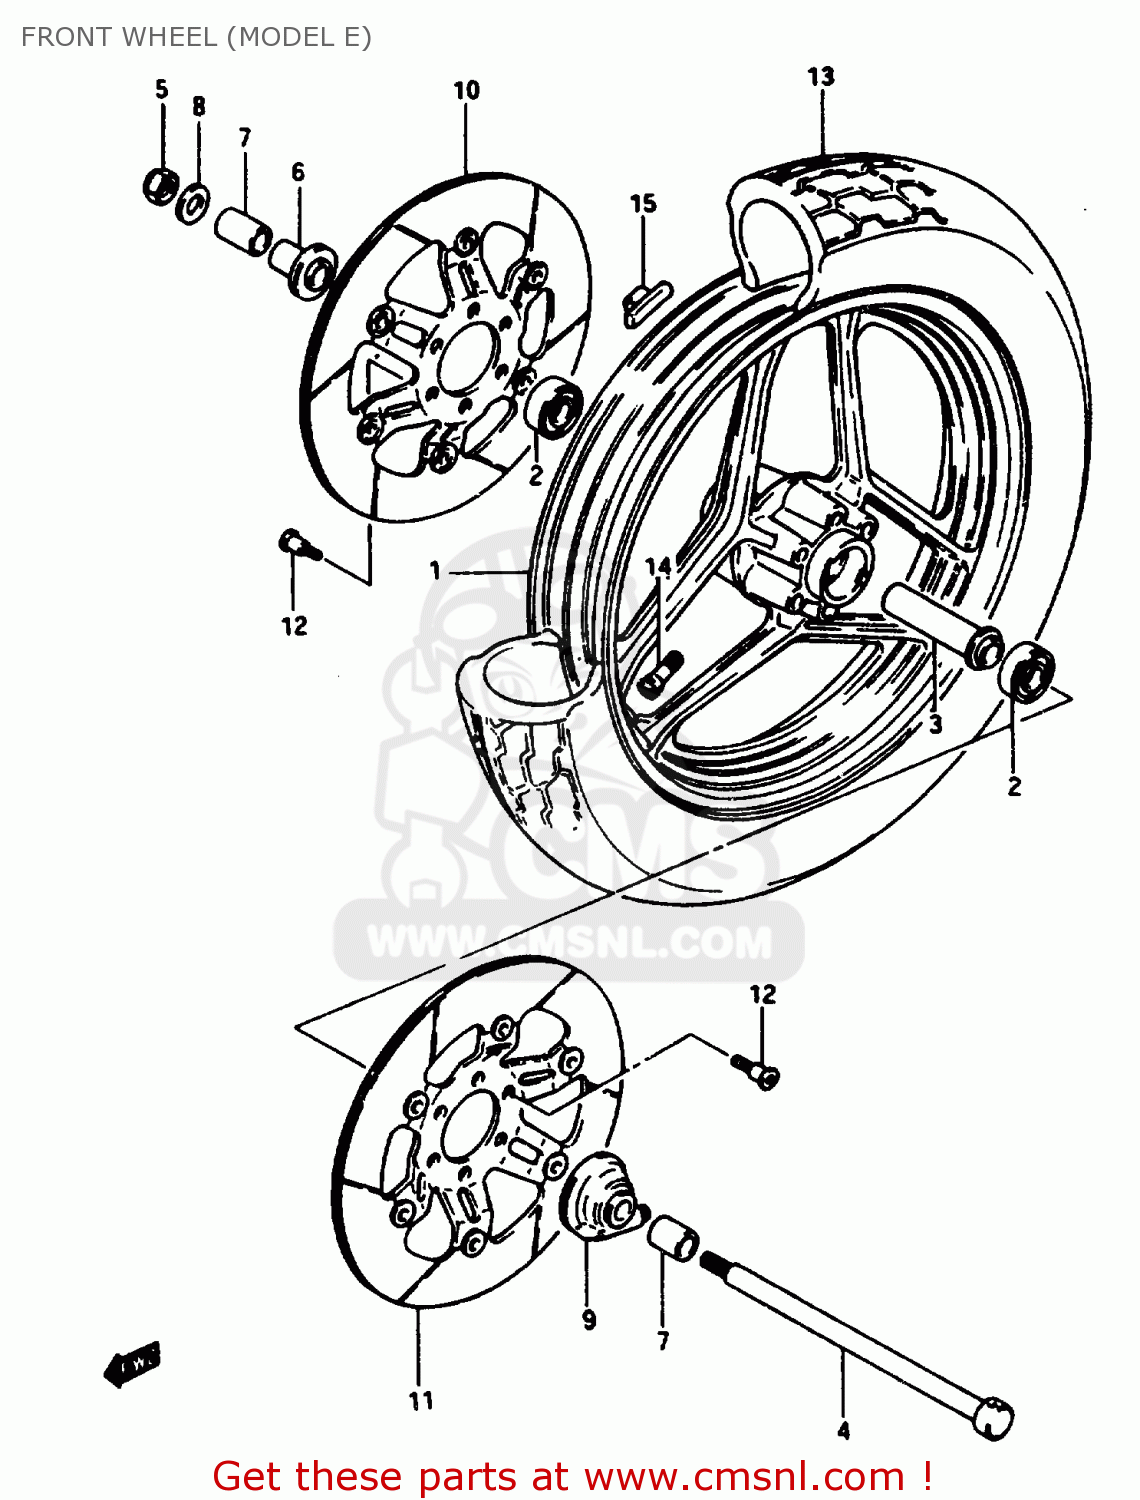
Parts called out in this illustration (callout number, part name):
1	CASTING WHEEL,
2	BEARING
3	SPACER,FRONT HUB BEARING
4	AXLE,FRONT
5	NUT
6	SPACER,FR AXLE,R
7	SPACER(15X22X30)
8	WASHER
9	BOX ASSY,SPEEDOMETER GEAR
10	DISC,BRAKE
11	DISC,BRAKE
12	BOLT
13	TIRE, T/L FRONT (110/90V16) BS
14	VALVE,TIRE
15	BALANCER,WHEEL
